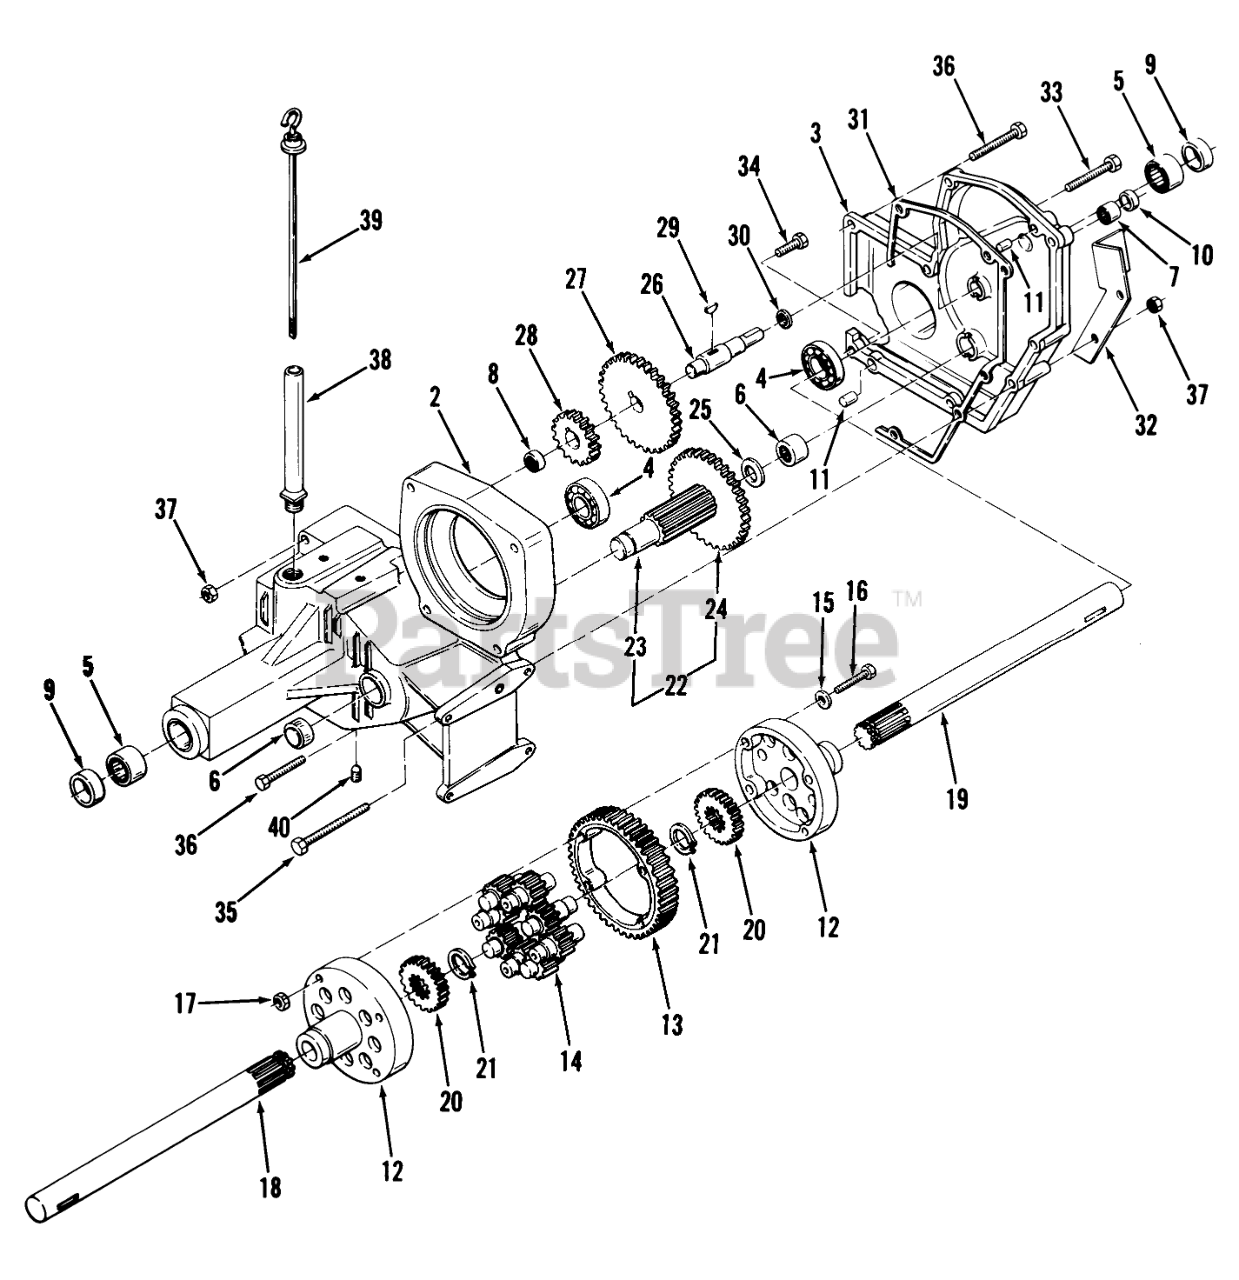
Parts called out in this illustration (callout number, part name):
1	Transaxle Complete
2	TRANS CASE RH
3	Case-Transaxle LH
4	BALL BRG 1 1/2 I.D.
5	BEARING
6	BEARING-NEEDLE
7	NEEDLE BEARING
8	BEARING-NEEDLE
9	SEAL-OIL
10	Seal
11	PIN-LOCATING
12	DIFFERENTIAL END CAP
13	GEAR-DIFFERENTIAL RING, 43T
14	GEAR-PINION, 11T
15	WASHER
16	BOLT-HEX
18	AXLE-REAR RH
19	AXLE-REAR LH
20	GEAR-AXLE DIFFERENTIAL
21	RING-SNAP
22	GEAR ASM
23	PINION SHAFT
25	WASHER-THRUST
26	Shaft
27	Gear 44 Tooth
28	GEAR 22T
29	WOODRUFF KEY
30	Race Thrust
31	GASKET-TRANSMISSION
32	Bracket-Brake
33	Bolt
34	Bolt
35	H H C S
36	Screw-Hex. Hd.
37	Nut
38	NIPPLE-TRANS FILL
39	ASSY-DIPSTICK
40	PLUG 1/4 PIPE ALLEN
